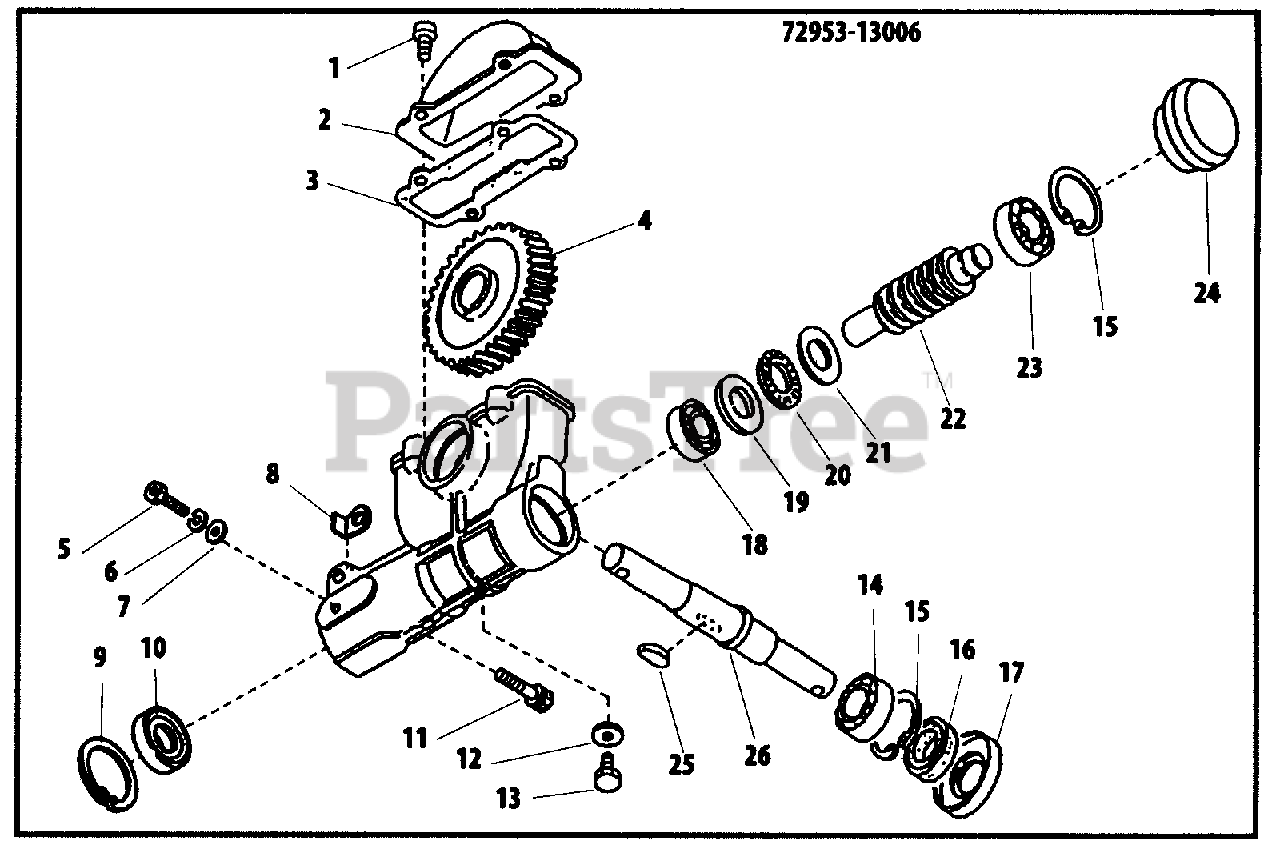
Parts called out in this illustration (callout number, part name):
1	SCREW
2	COVER, GEAR CASE
3	GASKET
4	GEAR, WORM
5	BOLT 5×12
6	WASHER, SPRING 5
7	WASHER, FLAT 5.5×10×0.8
9	RING, SNAP Ø22
10	SEAL, OIL
11	SCREW - 6×30
14	BEARING, BALL
15	RING, SNAP Ø28
16	SEAL, OIL
18	BEARING, BALL 6901
19	WASHER, THRUST
20	BEARING, NEEDLE
21	WASHER, THRUST
22	BEARING, NEEDLE
23	BEARING, BALL 6001
24	CAP
26	DRIVESHAFT
